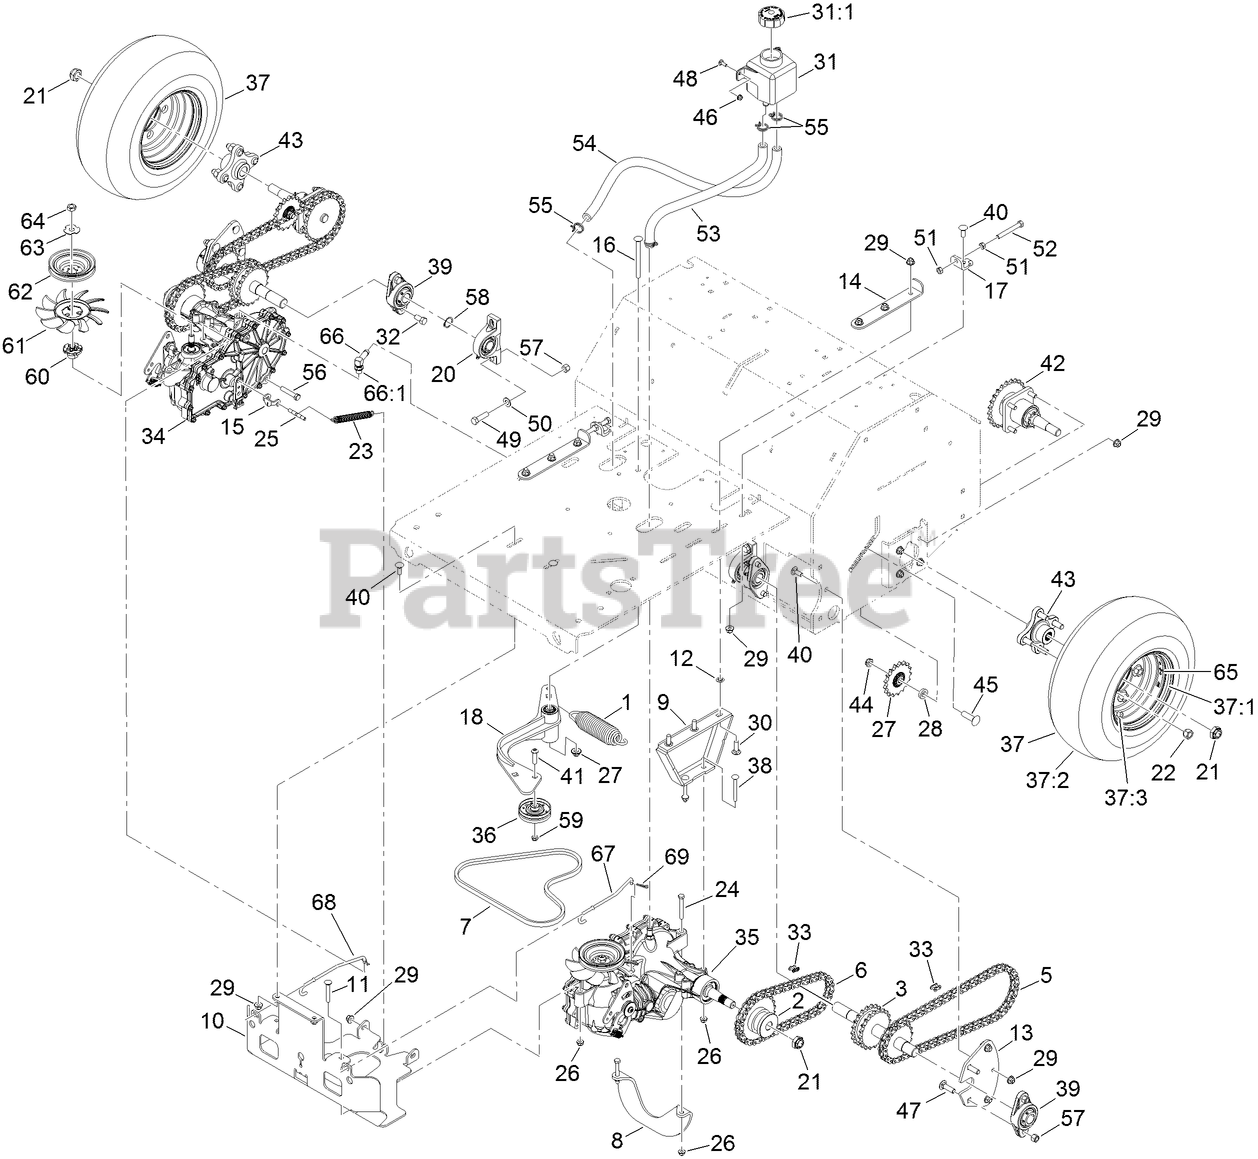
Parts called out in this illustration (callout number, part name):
1	SPRING-EXTENSION
2	HUB-DRIVE, CHAIN
3	JACKSHAFT
5	CHAIN-ROLLER, #50, 65 LINKS
6	CHAIN-ROLLER #50, 47 PITCHES
7	BELT-4L SECTION
8	BRACE-ANGLE
9	MOUNT-TRANSMISSION
10	GUARD-TRANSMISSION
11	BOLT-CARR
12	NUT-PUSH
13	PLATE-JACKSHAFT
14	PLATE-ADJUSTMENT, TRANSMISSION
15	YOKE-BRAKE, PARK
16	BOLT-CARR
17	BRACKET-HYDRO, ADJUST
18	IDLER ARM ASM
20	BEARING-PILLOW BLOCK
21	NUT-LOCK
22	NUT-LUG
23	SPRING-DOOR
24	SCREW-HH
25	PIN-BRAKE, PARK
26	NUT-HF, NI
27	SPROCKET-IDLER, 17T
28	WASHER
29	NUT-HF, NI
30	BOLT-CARR
31	TANK-HYD
31:1	CAP-RESERVOIR, HYD
32	SCREW-HH
33	LINK-CONNECTING
34	RH TRANSAXLE ASM (NO FAN)
35	LH TRANSAXLE ASM (NO FAN)
36	PULLEY-IDLER
37	WHEEL AND TIRE ASM
37:1	RIM-GRAY
37:3	STEM-VALVE
38	SCREW-CARR
39	BEARING-FLANGE, 2 BOLT
40	BOLT-CARR
41	SCREW-HSBH
42	AXLE AND BEARING ASM
43	HUB-OFFSET
44	NUT-LOCK, NI
45	SCREW-CARR
46	NUT-HF
47	BOLT-CARR
48	BOLT-CARR
49	SCREW-HH
50	WASHER-FLAT
51	NUT-HEX
52	SCREW-HH
53	HOSE-HYDRAULIC
54	HOSE-HYDRAULIC
55	CLAMP-HOSE
56	SCREW-HH
57	NUT-LOCK, NI
58	RING-RETAINING
59	NUT-LOCK, NI
60	HUB-PULLEY
62	PULLEY
63	WASHER-SLOTTED
64	NUT-HJ
65	DECAL-HUB, WHEEL
66	FITTING-ELBOW, 90
66:1	O-RING
67	LINKAGE-BYPASS, LH
68	LINKAGE-BYPASS, RH
69	PIN-COTTER
